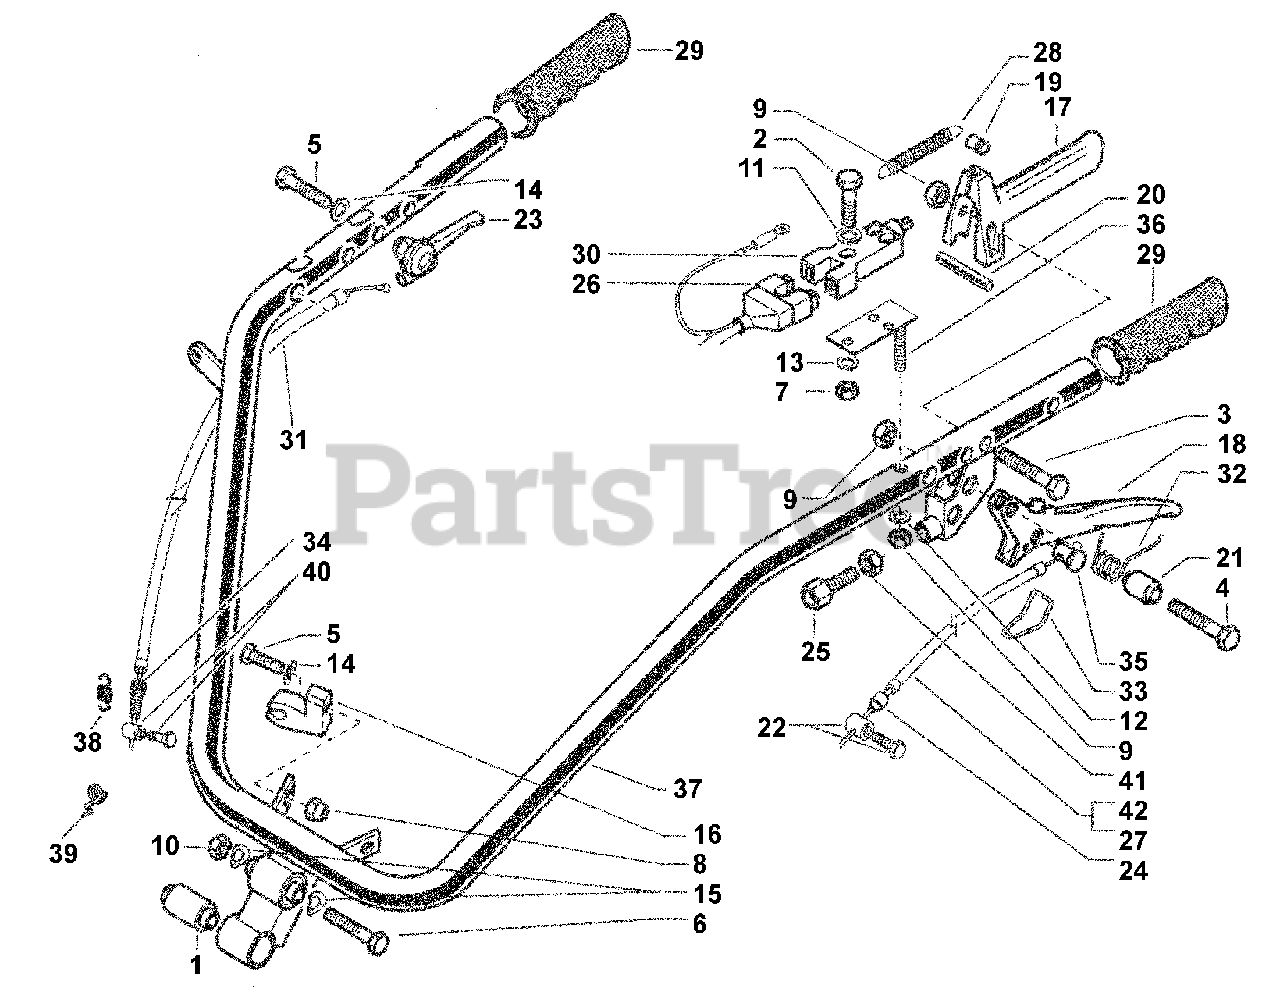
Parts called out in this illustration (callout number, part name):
1	SILENTBLOCK
2	SCREW TE M4X25
3	SCREW, TE M6X45
4	SCREW, M6X25
5	SCREW, M8X35
6	SCREW, M10X80
9	NUT, SELF LOCKING M6
11	FLAT WASHER, M4.3
12	WASHER, FLAT 6.4
13	LOCK WASHER, M4.3
14	WASHER, M8.4
15	WAVE WASHER, M10.4
16	SUPPORT, CONTROL ROD
17	MOTOR STOP LEVER
18	CLUTCH LEVER
20	LEVER STOP FOR MOTOR STOP
21	LEVER SPACER
22	CLAMP, CABLE
23	THROTTLE LEVER
25	SCREW, ADJUSTING, M8
26	SWITCH WIRING HARNESS
27	CLUTCH CABLE
30	STOP SWITCH
31	THROTTLE CABLE
32	LEVER SPRING
34	CABLE ADJUSTER
36	SWITCH PLATE
